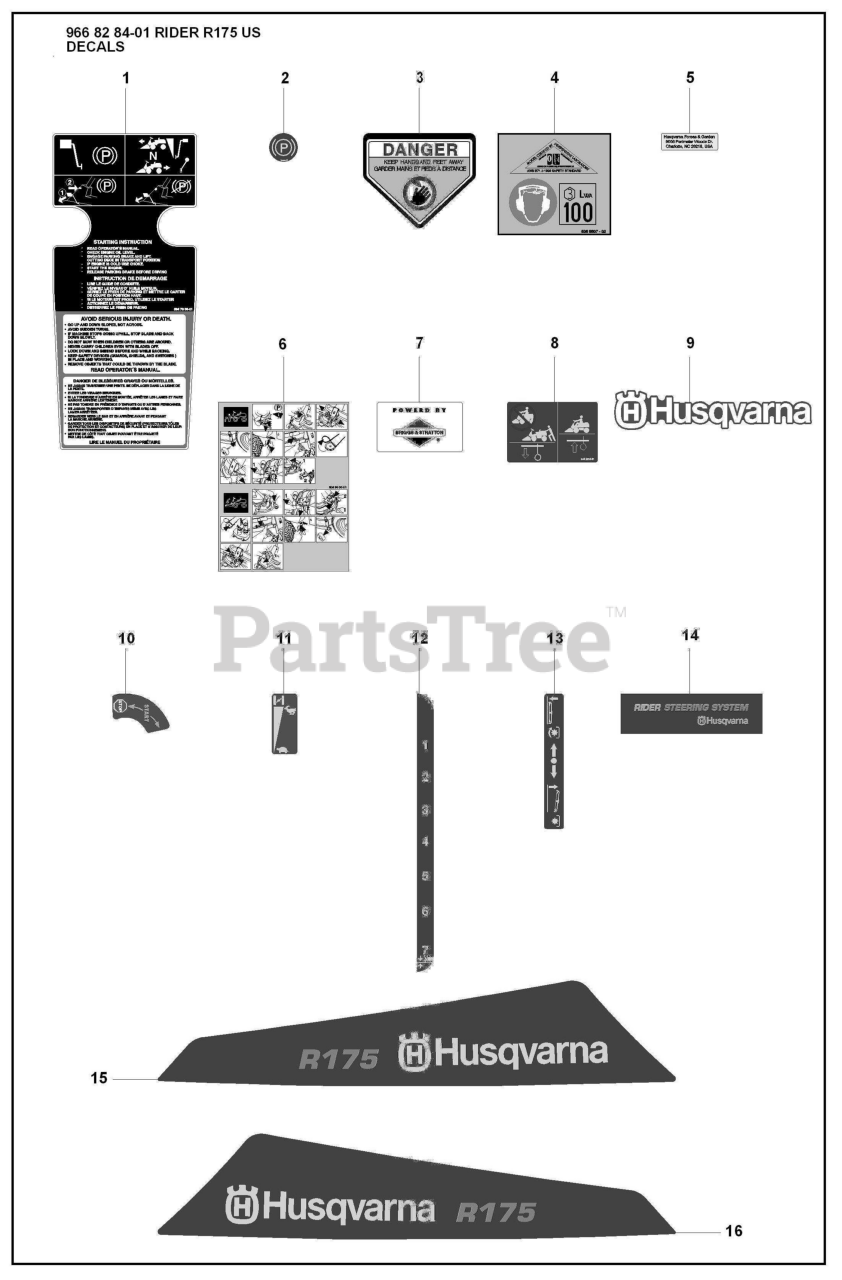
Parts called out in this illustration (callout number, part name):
4	REPL BY 506 88 07-03
15	LABEL
16	LABEL
